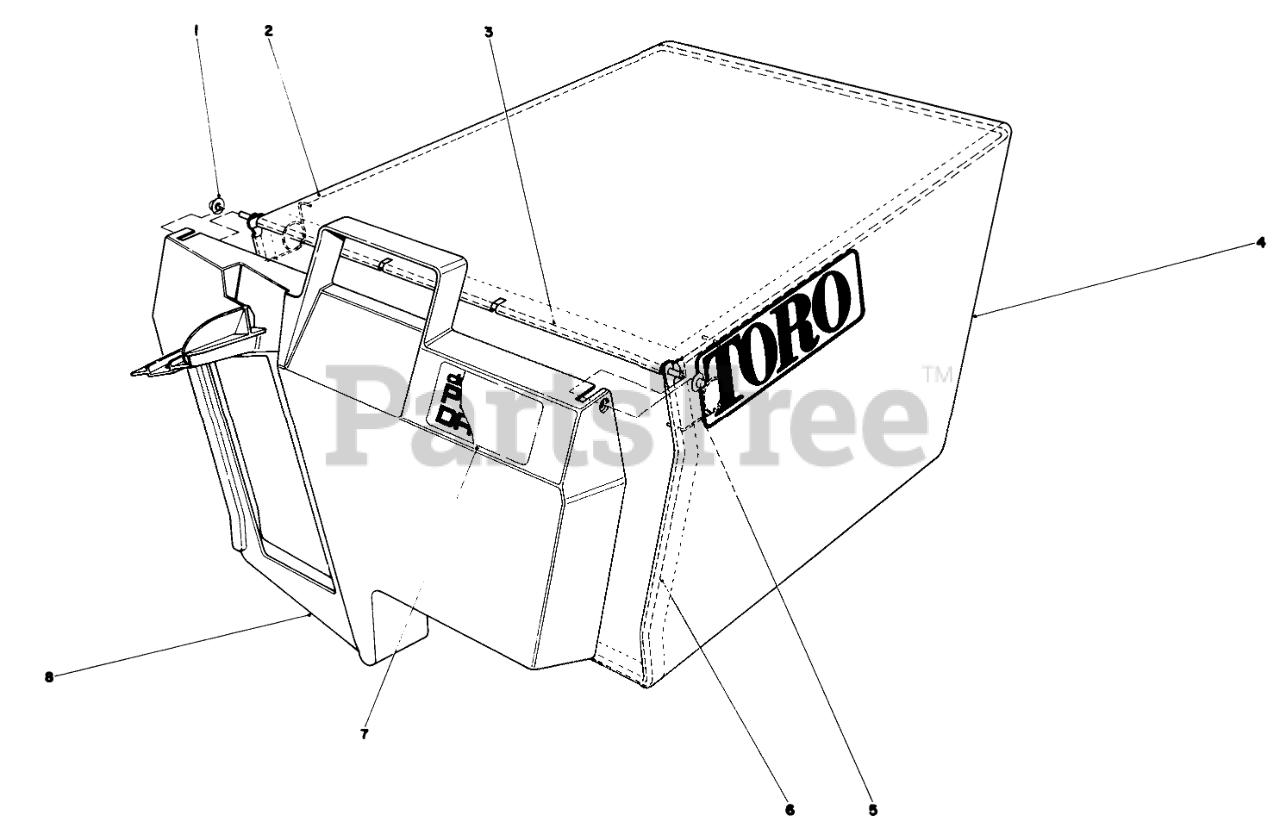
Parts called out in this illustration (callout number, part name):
1	NUT-PUSH
2	Bag Frame Upper
3	HINGE-DOOR, BAG
4	Bag
5	SPRING
6	FRAME-BAG
7	BAG DOOR DECAL
8	Door Grass Bag
